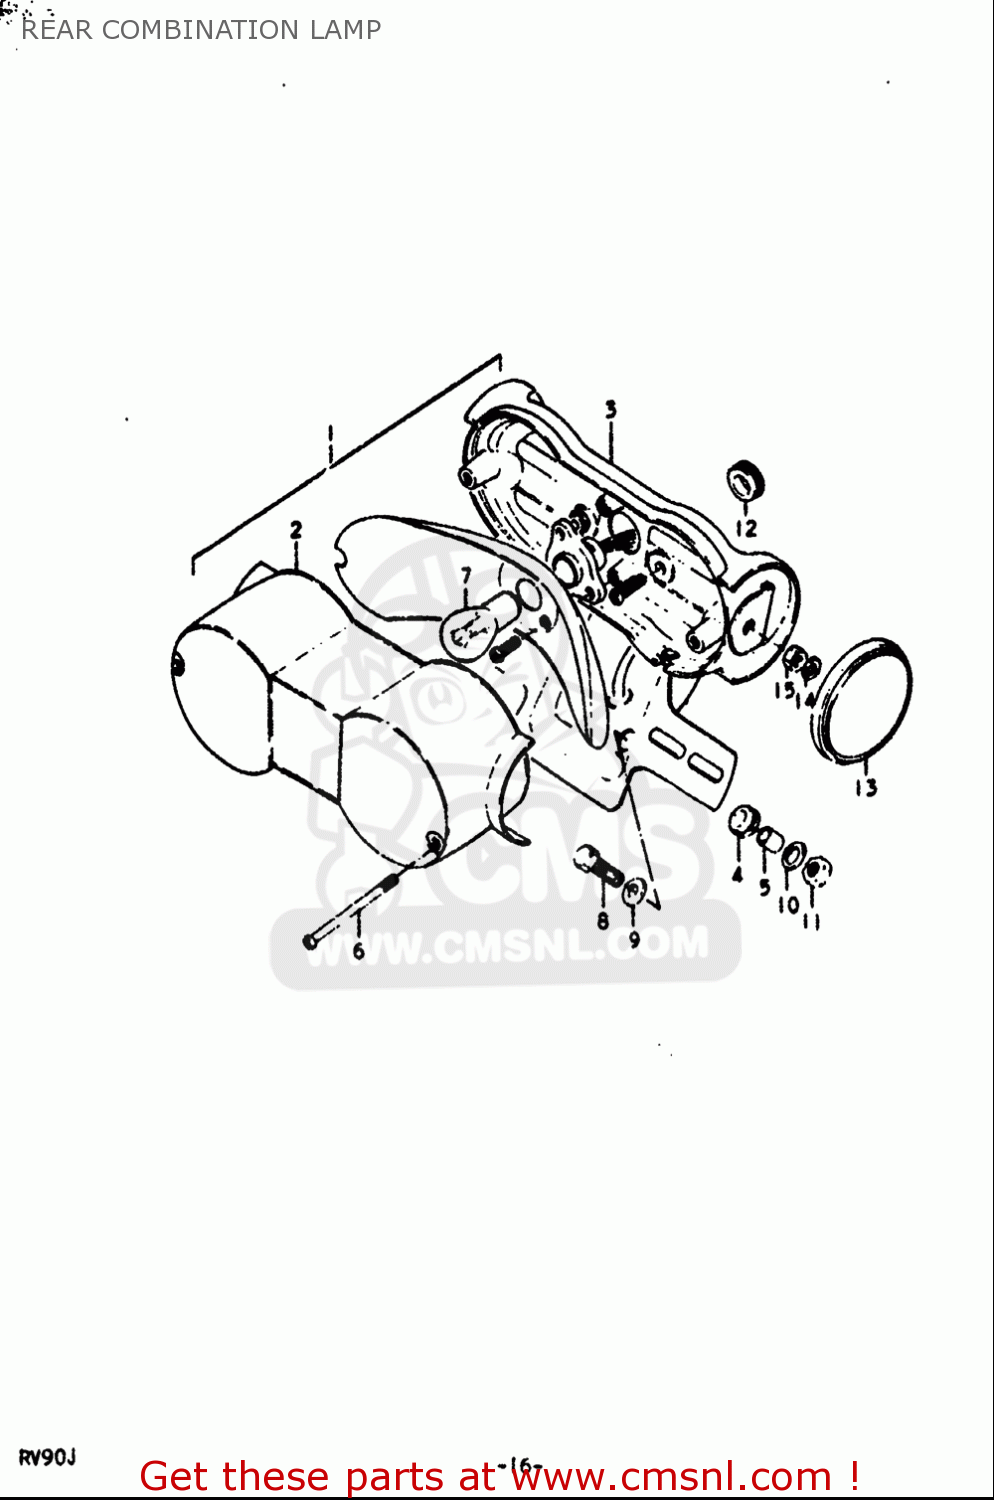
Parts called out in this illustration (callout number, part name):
2	LENS,RR COMBINATION LAMP
4	CUSHION
5	SPACER
6	SCREW
7	BULB(6V17/5.3W,STANLEY,A4813)
8	BOLT
9	WASHER(6.5X20X1.6)
10	WASHER
11	NUT
12	GROMMET
14	WASHER,LOCK
15	NUT
